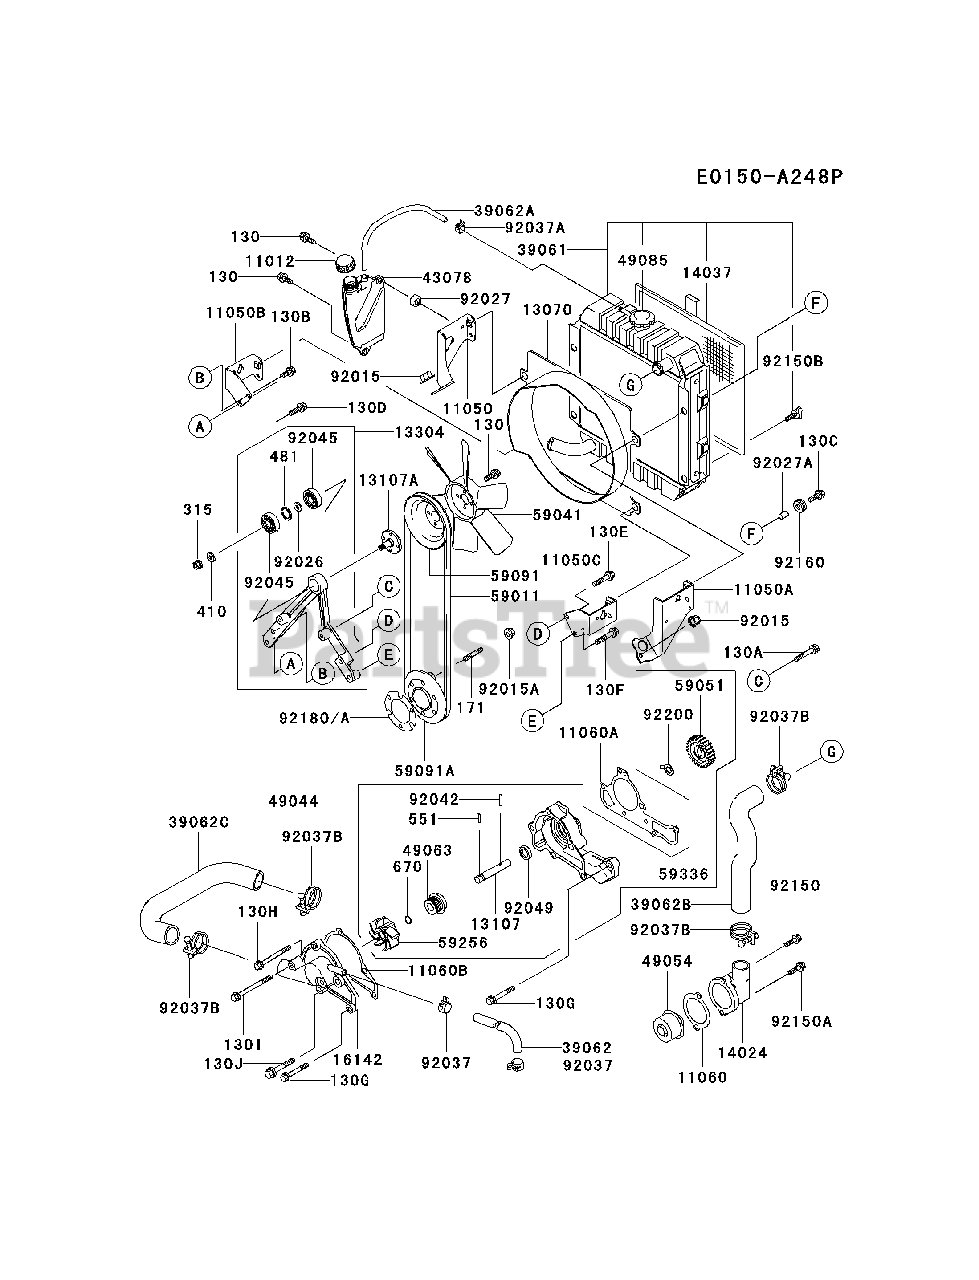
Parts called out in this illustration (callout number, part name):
130	BOLT-FLANGED,6X16
130A	BOLT-FLANGED,6X35
130B	BOLT-FLANGED,8X20
130C	BOLT-FLANGED,8X25
130D	BOLT-FLANGED,8X30
130E	BOLT-FLANGED,8X40
130F	BOLT-FLANGED,8X45
130G	BOLT-FLANGED,6X45
130H	BOLT-FLANGED,6X65
130I	BOLT-FLANGED,6X75
130J	BOLT-FLANGED,8X70
171	BOLT-STUD,8X18
315	NUT-HEX-FINE,10MM
410	WASHER-PLAIN-SMALL,10MM
481	CIRCLIP,28MM
551	PIN-DOWEL,3X14
670	O RING,7MM
92045	BEARING-BALL,6001DDUC3
92180	SHIM,T=0.6
92180A	SHIM,T=1.2
